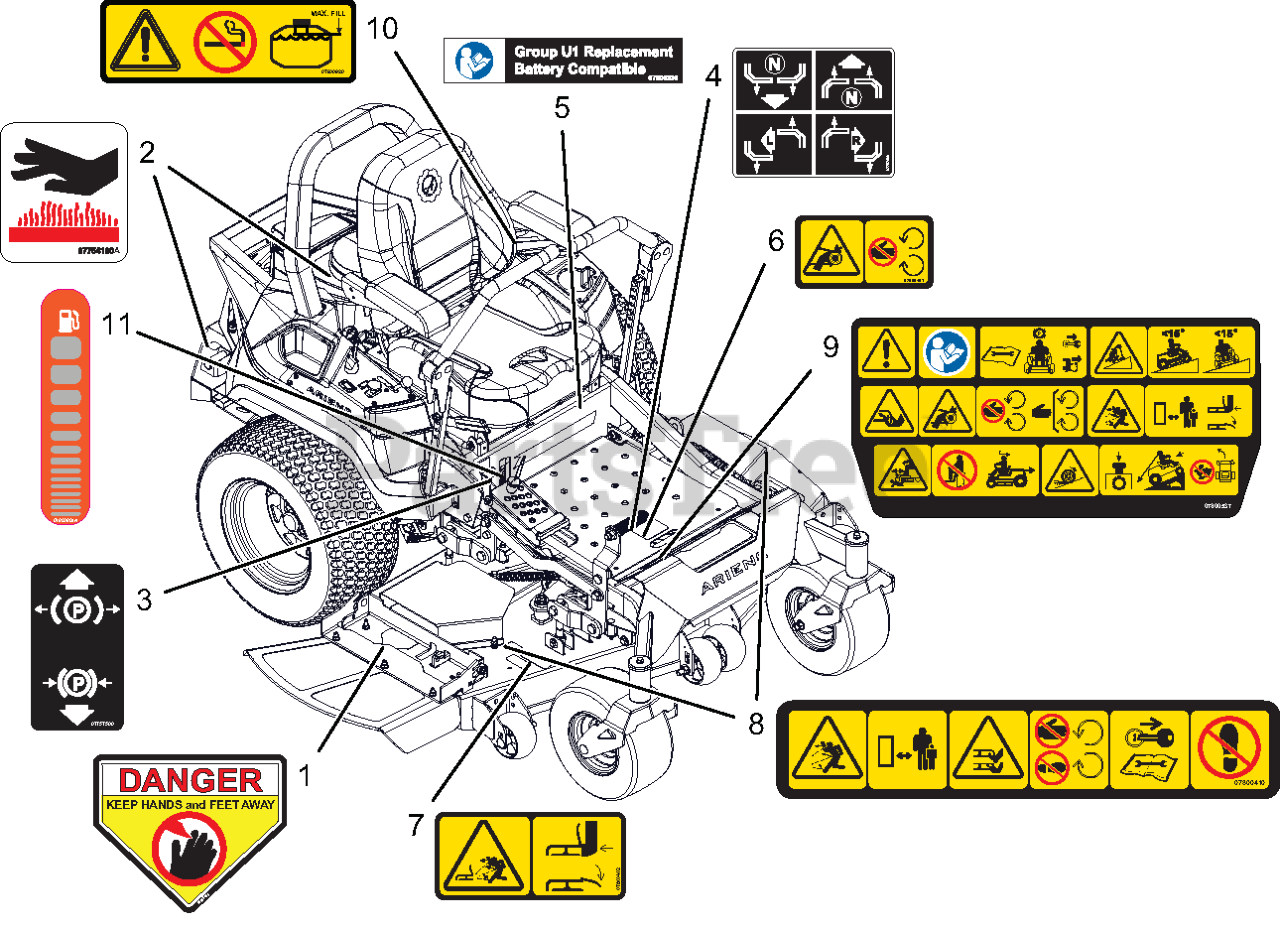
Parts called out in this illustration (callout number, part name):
1	DECAL, DANGER
2	DECAL, HOT SURFACE
3	DECAL, PARKING BRAKE LEVER
4	DECAL, INSTRUCTIONAL-STEERING
5	DECAL, U1 BATTERY REPLACEMENT
6	DECAL, SAFETY - GUARDING
7	DECAL, SAFETY - DECK GUARDING
8	DECAL, DECK SAFETY
9	DECAL, MAIN SAFETY
10	DECAL, FUEL WARNING
11	DECAL, ARIENS FUEL LEVEL
